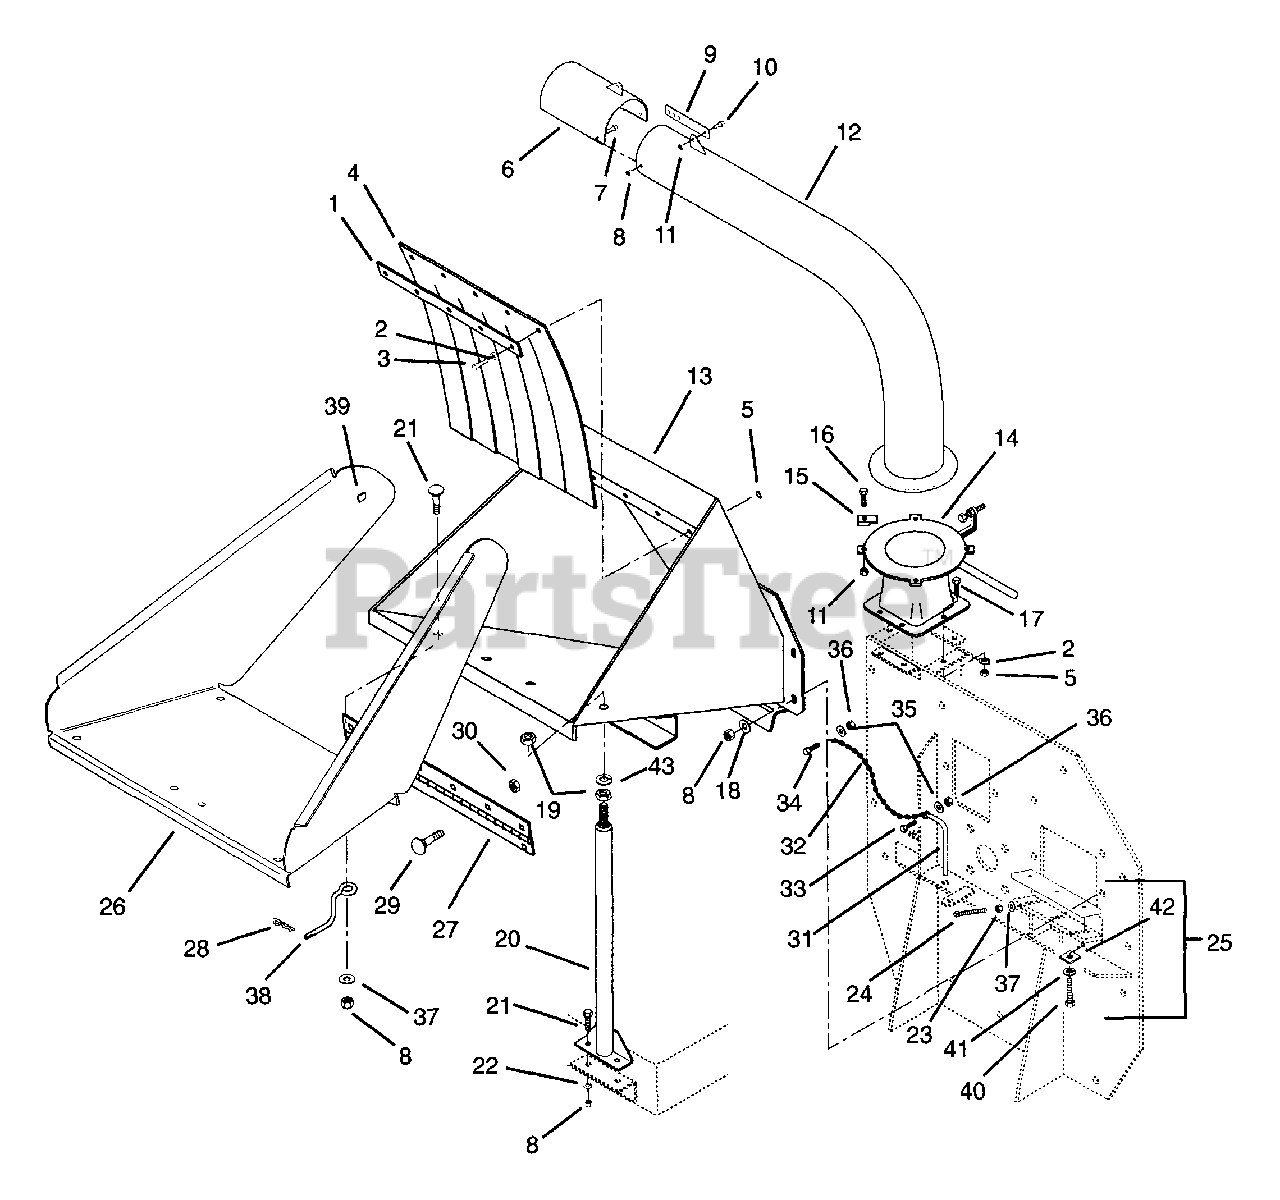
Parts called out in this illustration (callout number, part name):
1	Brace
2	Washer-Flat-Steel .312 x .734 x .065
3	Bolt-Hex .25-20 x .75 Grade 5
4	Rubber Flap
5	Nut-Locking-Center .25-20
6	Deflector
7	Bolt-Hex .38-16 x 1.0 Grade 5
8	Nut-Locking Center .38-16
9	Deflector Arm
10	Bolt-Hex .31-18 x 1.00 Grade 5
11	Nut-Locking Center .31-18
12	Discharge Chute
13	PTO-Hopper Weldment
14	Discharge Neck
15	Clamp
16	Bolt-Hex .31-18 x 1.25 Grade 5
17	Bolt-Hex .25-20 x 1.00 Grade 5
18	Washer-Flat-Steel .406 x 1.000 x .188
19	Nut-Locking-Center .75-10
20	Hopper Stand
21	Bolt-Hex .38-16 x 1.00 Grade 5
22	Washer-Flat-Steel .438 x 1.00 x .083
23	Nut-Hex .38-16
24	Screw-Set .38-16 x 3.50
25	Bed Knife Kit 210/PTO
26	Safety Bonnet Weldment
28	Pin-Hair Internal .15 x .43 x 2.75
29	Bolt Round Head Square Neck .25-20 x .50 Grade 5
30	Nut-Locking-Center .25-20
31	Pin-Arbor Shaft Lock
32	Chain-14 Straight Link
33	Screw-Machine 10-24 x 1.00
34	Screw-Machine 10-24 x .75
35	Washer-Flat-Steel .219 x .50 x .049
36	Nut-Locking-Nylon 10-24 with Insert
37	Washer-Flat-Steel .438 x 1.00 x .083
38	Bonnet Positioner
40	Bolt-Hex .38-16 x 1.25 Grade 8
41	Washer-Locking .38 x .094
42	Double Hole Washer
43	Washer-Locking .75 x .188
